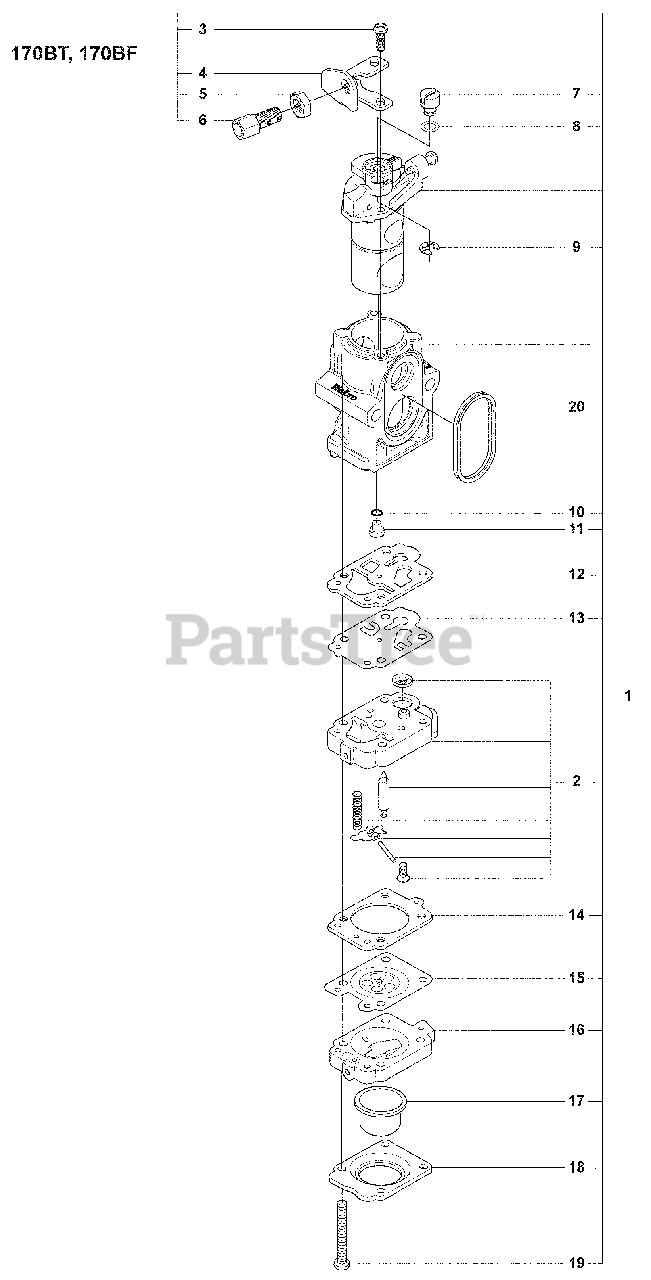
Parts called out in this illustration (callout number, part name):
1	Carburetor
2	Pump Body, A
3	Screw
5	Nut
6	Screw
7	Swivel
8	Washer
10	O-Ring
12	Gasket
13	Diaphragm
14	Gasket
15	Diaphragm
16	Diaphragm
17	Primer Blub
18	Cover
19	Screw
20	Ring
